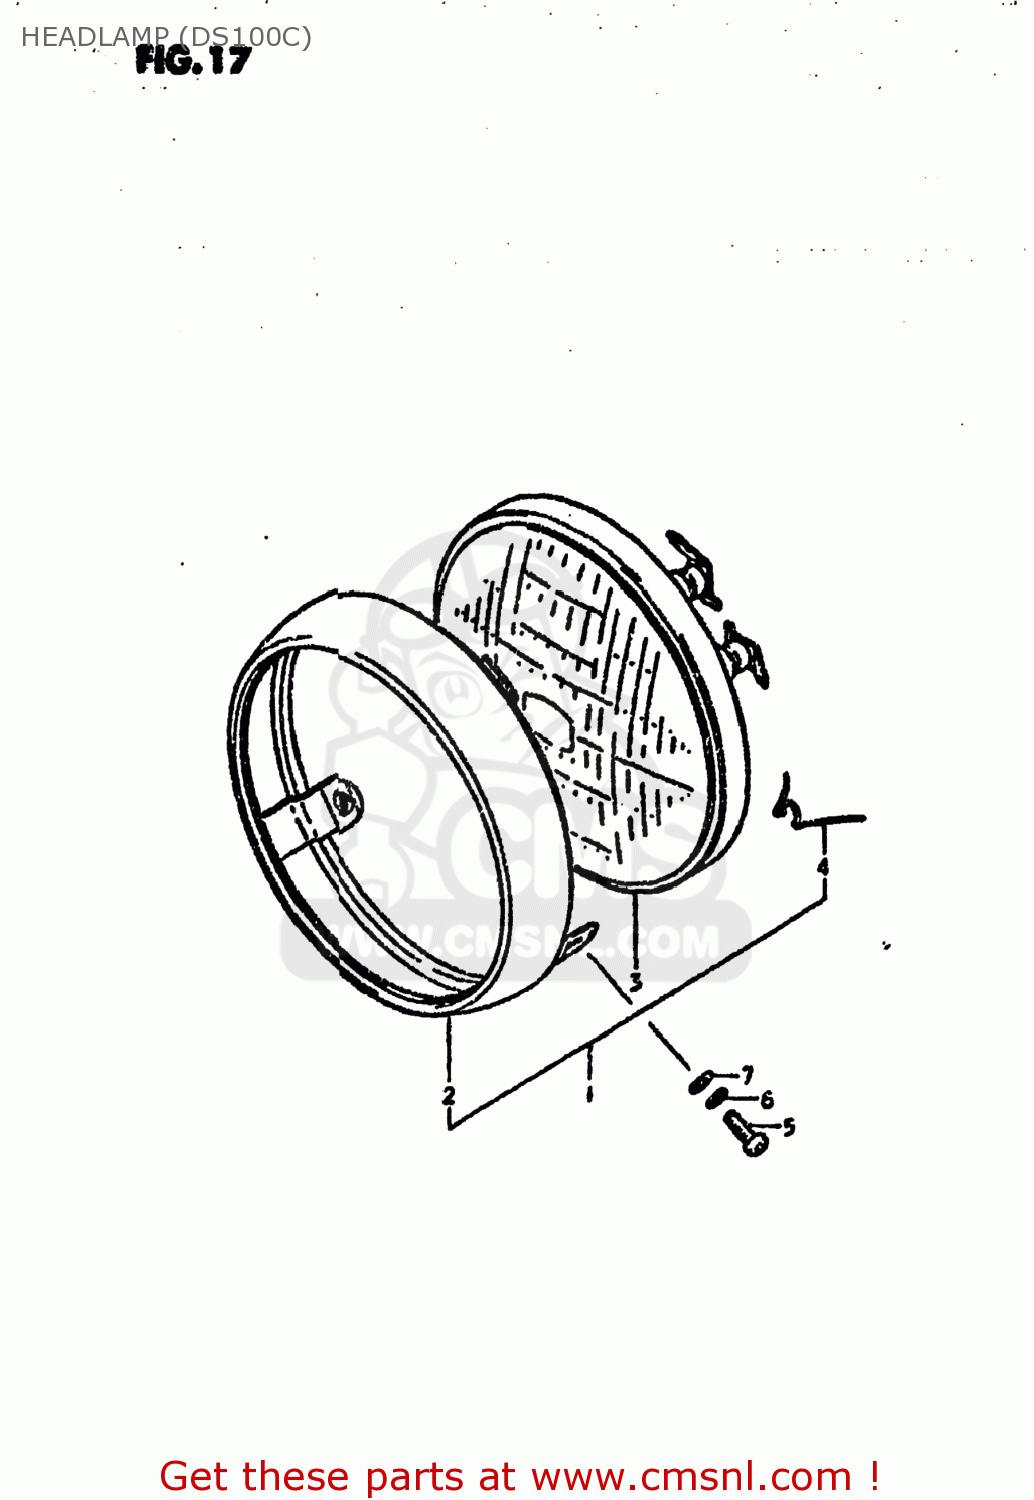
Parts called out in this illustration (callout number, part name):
1	LAMP ASSEMBLY,HEAD
2	RIM,HEADLAMP
3	LAMP UNIT
4	SPRING,HEADLAMP UNIT
5	SCREW
6	LOCK WASHER
7	WASHER
